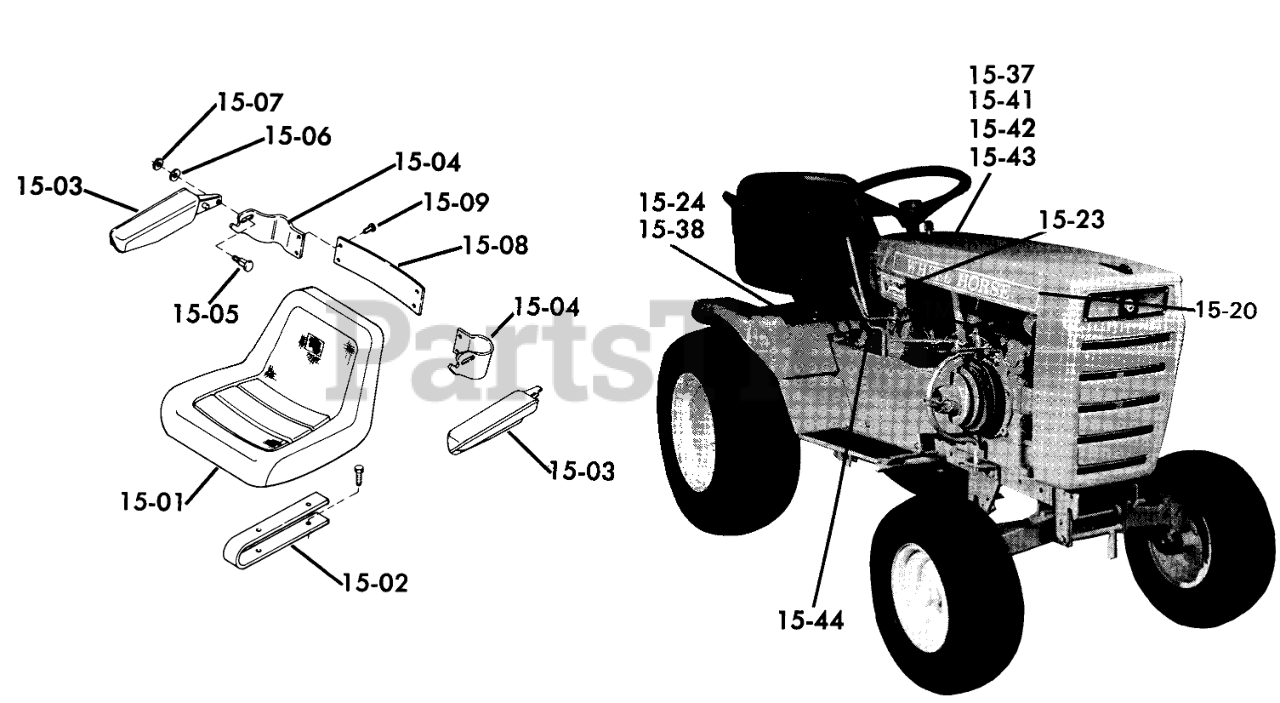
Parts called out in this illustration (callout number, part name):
15-01	Seat
15-02	Seat Spring
15-02	Bolt
15-02	Nut
15-02	Lockwasher
15-03	Arm R.H.
15-03	Arm L.H.
15-04	Bracket R.H.
15-04	Bracket L.H.
15-05	Bolt (Slide Pivot)
15-06	Washer, Bellville
15-07	Nut (Pivot)
15-08	Bracket-Arm Brace
15-09	Screw
15-20	Decal
15-23	DECAL C 160
15-23	Decal
15-24	DECAL-WHEEL HORSE
15-37	Lockwasher
15-38	Decal-Maintenance
15-41	DECAL PTO SPD. CONT
15-42	DECAL-HAND LIFT
15-43	Decal-Caution
15-44	Decal-Parking Brake
15-44	Decal
